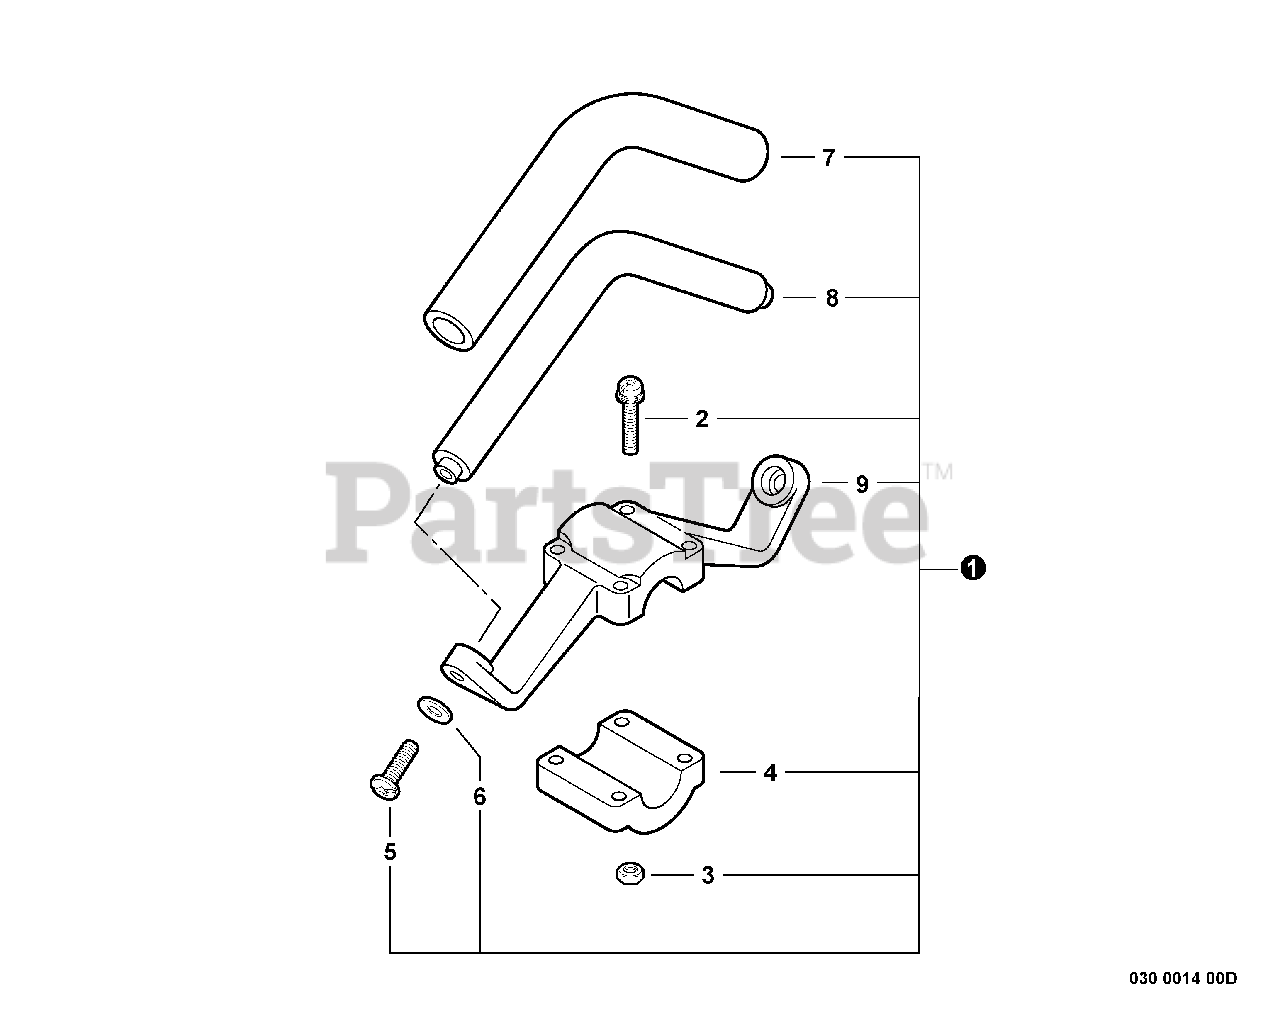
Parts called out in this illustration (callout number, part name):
1	HANDLE ASSY, FRONT
2	SCREW 5×35
3	NUT M5
4	BRACKET, HANDLE - LOWER
5	SCREW, TAPPING 5×20
6	WASHER, FLAT 5.5×10×0.8
7	GRIP, HANDLE
8	HANDLE, SUPPORT
9	BRACKET, HANDLE
